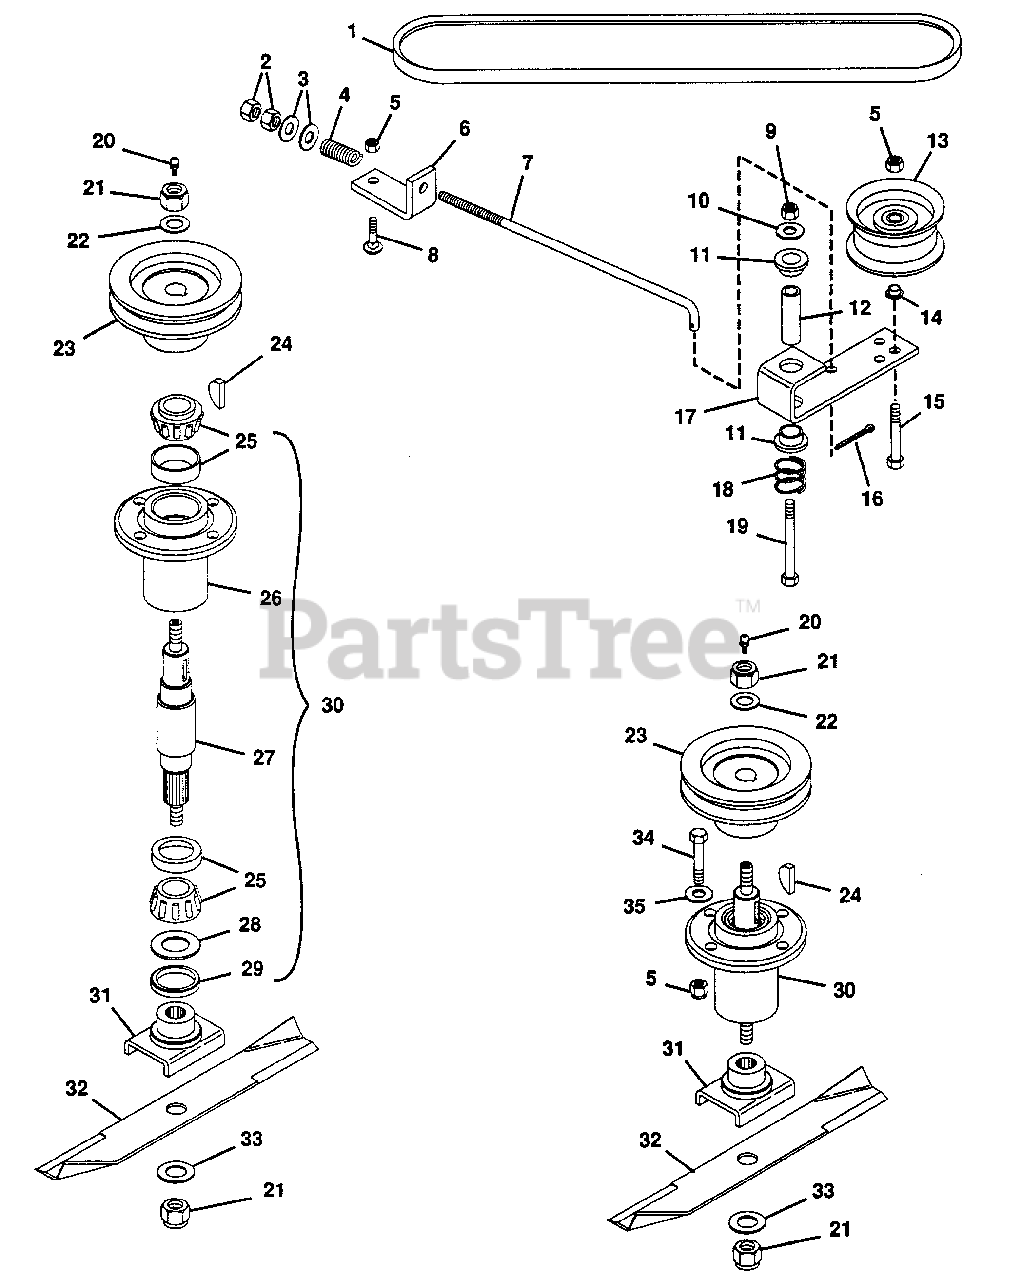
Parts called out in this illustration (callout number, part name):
1	Belt, Pro-36 Mower
2	Nut, Hex 3/8-24
3	Washer, Flat .406x.812x.065
4	Spring, Comp. 1x.78x338 Lb/N
5	Nut, Lock 3/8-16
6	Bracket, Belt Tensioner
7	Rod, Idler
8	Bolt, 3/8-16x1.00 Rd Hd Sq Nk
9	Nut, Lock 1/2-13
10	Washer, Flat .531x1.250x.100
11	Bush., Flg. .764x1.47x.560 Ny.
12	Bush., St. .560x.750x2.44 Stl.
13	Pulley, Idler
14	Bush., Flg. .406x.880x.270 Brz.
15	Bolt, Hex 3/8-16x2.25
16	Pin, Cotter .09x.75
17	Arm, Idler Pivot
18	Spring, Comp. 1x.80x36 Lb/N
19	Bolt, Hex 1/2-13x3.25
20	Fitting, Lube 1/8
21	Nut, Lock 5/8-11
22	Washer, Flat .687x1.312x.122
23	Sheave, Spindle
24	Key, Woodruff 1/4x1 Hard #15
25	Assembly, Bearing
26	Housing, Bearing
27	Shaft, Spindle
28	Washer, Flat .975x1.970x.030
29	Seal, Steel
30	Assembly, Spindle
31	Weldment, Blade Cradle
32	Blade, 36" Mower
33	Washer, Flat .656x1.312x.095
34	Bolt, Hex 3/8-16x1.25
35	Washer, Flat .438x1.000x.083
